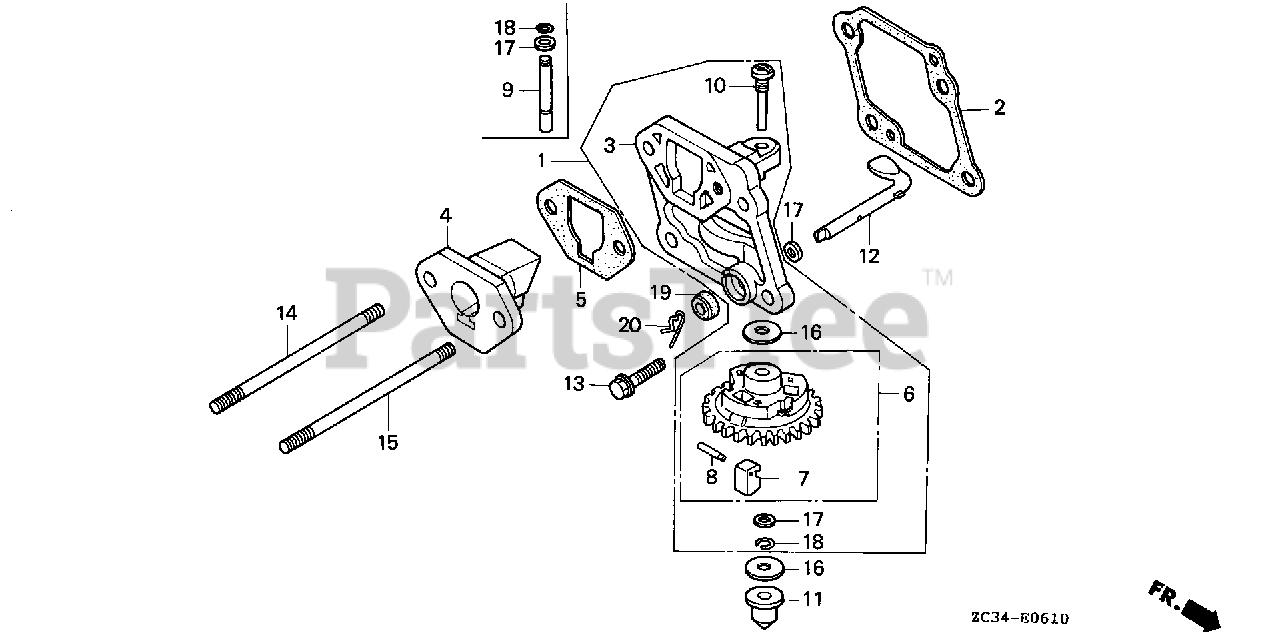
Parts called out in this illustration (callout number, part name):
1	COVER SET, CRANKCASE
2	GASKET, CRANKCASE
3	COVER SET, CRANKCASE
3	COVER, CRANKCASE
4	VALVE, REED
5	GASKET, REED VALVE
6	HOLDER ASSY., GOVERNOR
7	WEIGHT, GOVERNOR
8	PIN, GOVERNOR WEIGHT
9	SHAFT, GOVERNOR HOLDER
10	SHAFT, GOVERNOR HOLDER
11	SLIDER, GOVERNOR
12	SHAFT, GOVERNOR ARM
13	BOLT, FLANGE (6X20)
14	BOLT, STUD (6X85)
15	BOLT, STUD (6X87)
16	WASHER (5.2X16)
17	WASHER (5.2X9)
18	CLIP, GOVERNOR HOLDER
19	OIL SEAL (5X11X5)
20	PIN, LOCK (8MM)
